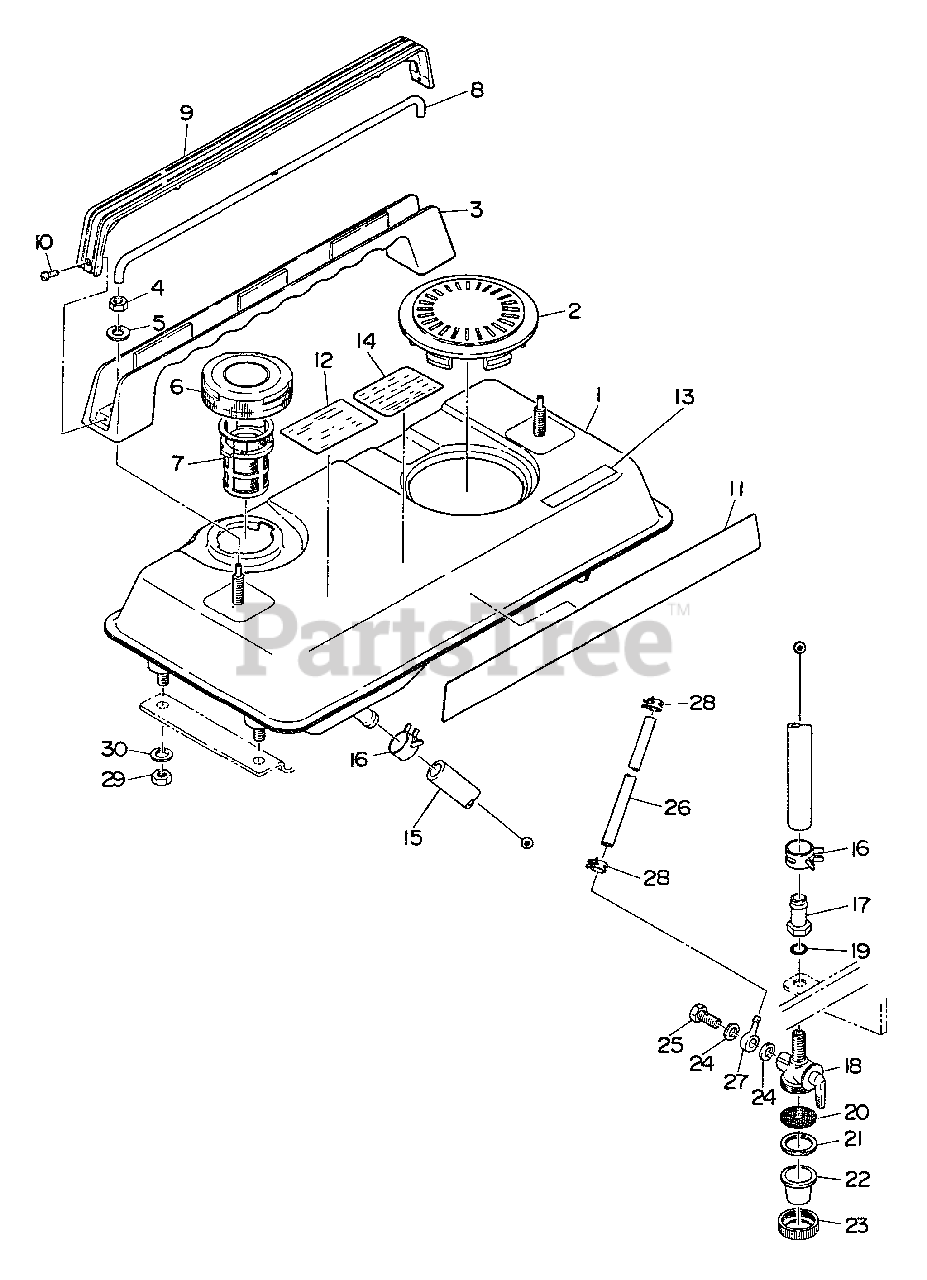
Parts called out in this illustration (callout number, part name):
1	FUEL TANK ASSY
2	PLUG COVER
3	HANDLE
4	NUT
5	LOCKWASHER
6	CAP ASSY
7	FILTER, FUEL
8	PIPE, BREATHER
9	HANDLE COVER
10	SCREW - PAN HEAD
11	LABEL - TRADE MARK
12	LABEL - CAUTION
13	LABEL - SPARK ARRESTER
14	LABEL - DANGER
15	RUBBER PIPE (11.5×17.5×230 MM)
16	CLAMP, HOSE
17	CLAMP, HOSE
18	FILTER, FUEL
19	O-RING
23	NUT, LOCK
24	FIBER PACKING
25	BOLT, BANJO
26	RUBBER PIPE (6×12×160 MM)
27	BOLT, BANJO
28	CLAMP, HOSE
29	NUT
30	LOCKWASHER
